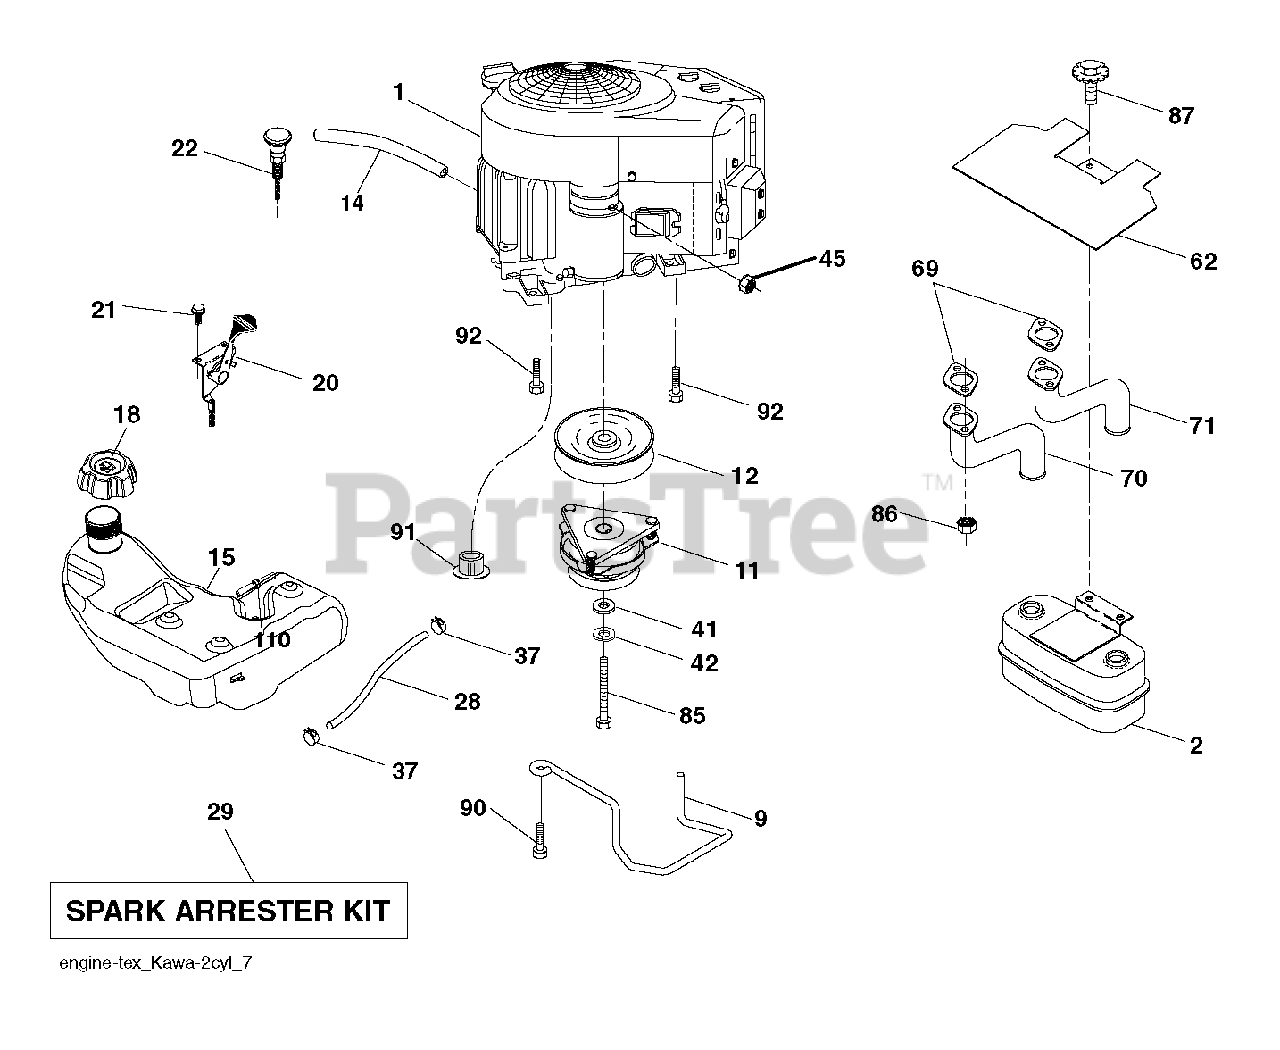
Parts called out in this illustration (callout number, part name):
2	MUFFLER.ASM.TWN.EXTNDED.DFLCTR
9	KEEPER BELT ENGINE
11	CLUTCH MZ ZTR GT.48/54"1.125"
12	PULLEY ENGINE
14	TUBE, DRAIN OIL ASM.
15	TANK.ASM.4.GAL.EPA.ONE.PORT
18	CAP.ASM.FL.RITCH.3"E10.SYM.498
20	CONTROL.THROTTLE.COBRA.BLACK
21	SCREW.#10 X 0.750.BOS
22	CONTROL.CHOKE.ERGO.PUSH-IN.BLA
28	LINE.FUEL.64"REAR.EMIS
29	KIT.SPARK ARRESTOR 794945 B&S
37	HOSE CLAMP
42	LOCKWASHER
45	NUT
62	SHIELD.HEAT.MUFFLER
70	TUBE.EXHAUST.LH.FR961/FR730
71	TUBE.EXHAUST.RH.FR961/FR730
85	BOLT HEX 7/16-20 X 3.75 GR. 5
86	NUT.HEX.FLANGE.TOPLOCK
87	BOLT, 5/16-18 X 1 3/4
90	SCREW 3/8-16X1
91	BUSHING.1.375OD
92	SCREW 3/8-16X1
